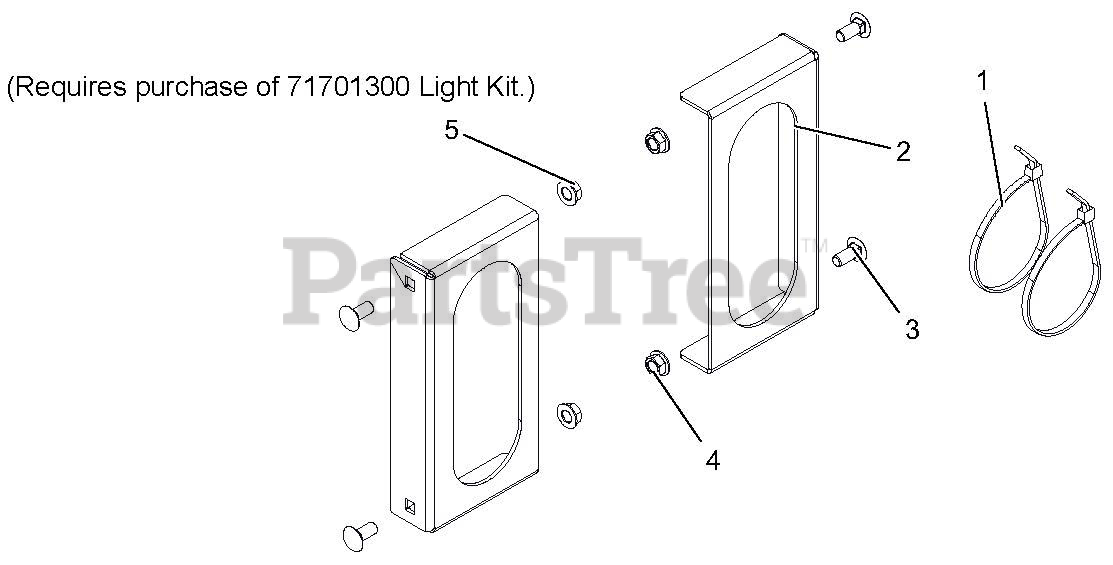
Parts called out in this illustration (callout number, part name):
1	TIE WRAP
2	MOUNT, TAILIGHT
3	@BLT-RDHDSQNK .31-18X.75 G5YZ
4	@NUT-LK-TOP-FLG .31-18 YWZC
5	@NUT-LK-TOP-FLG .31-18 YWZC
